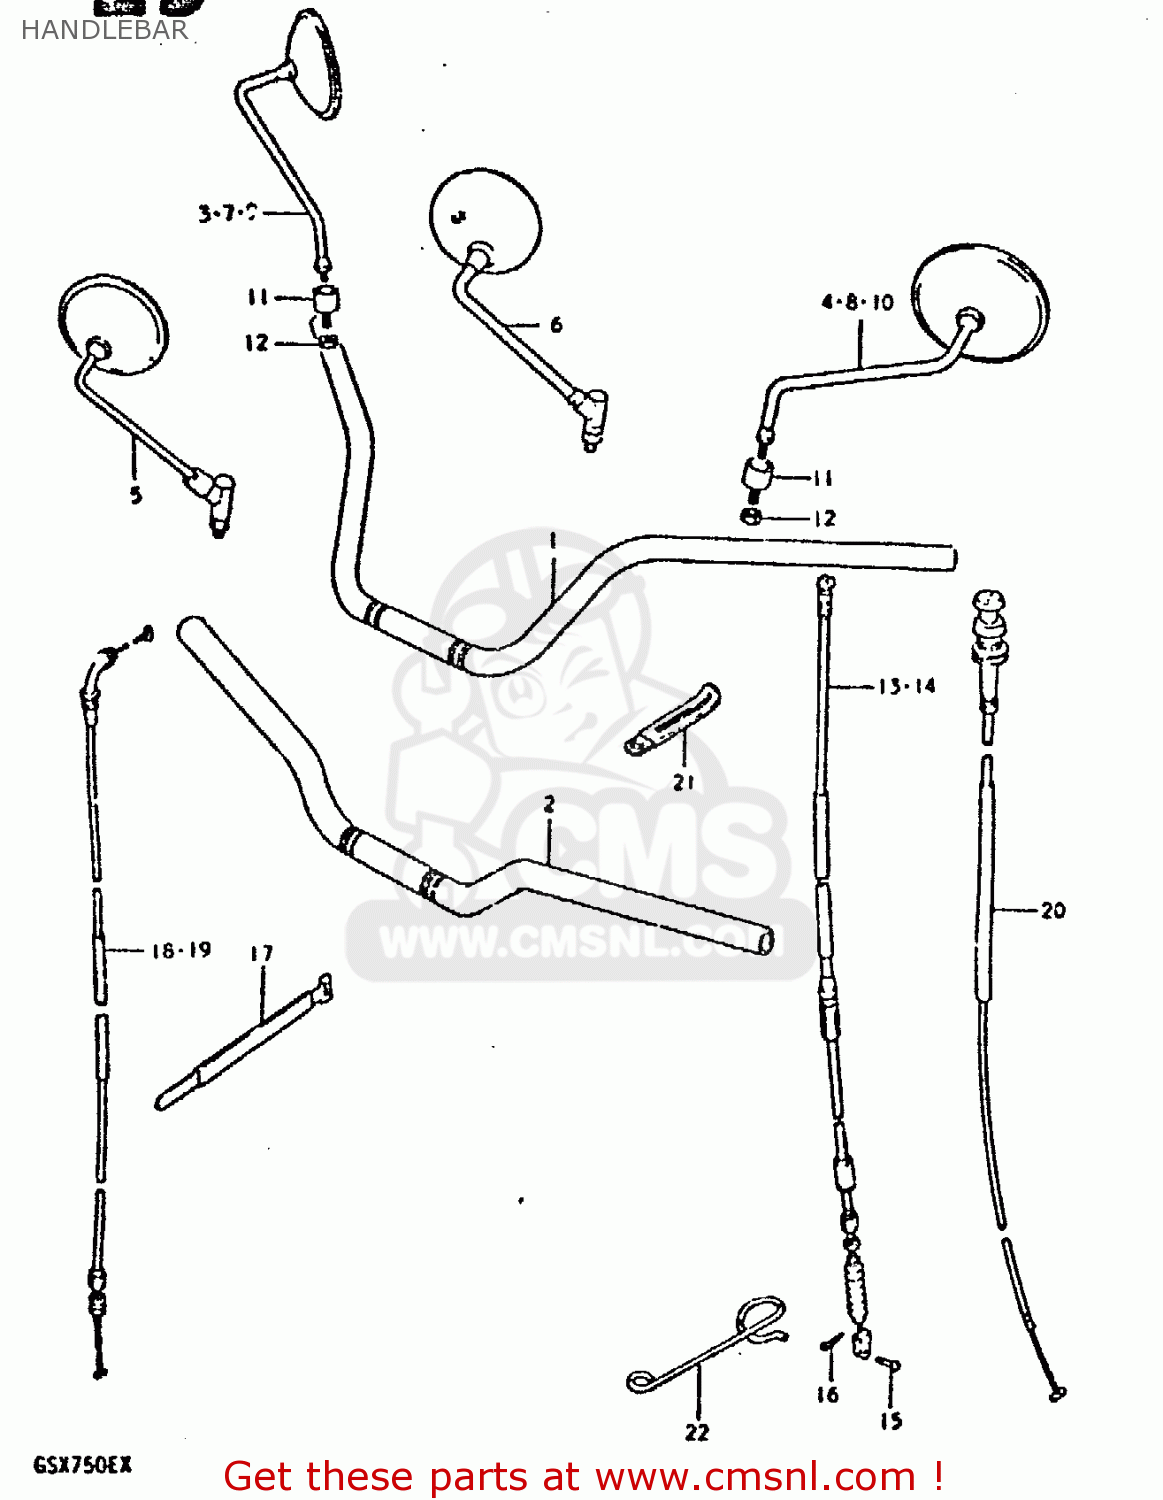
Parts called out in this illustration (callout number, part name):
1	HANDLEBAR
2	HANDLEBAR
5	MIRROR ASSY,RR VIEW
11	CUSHION,REAR VIEW MIRROR
12	NUT
13	CABLE ASSY,CLUTCH
14	CABLE,CLUTCH
15	PIN(L:15)
16	PIN
17	CLAMP
18	CABLE ASSEMBLY,THROTTLE
19	CABLE ASSEMBLY,THROTTLE
20	CABLE ASSEMBLY,STARTER
21	CLAMP
22	GUIDE,CLUTCH CABLE
